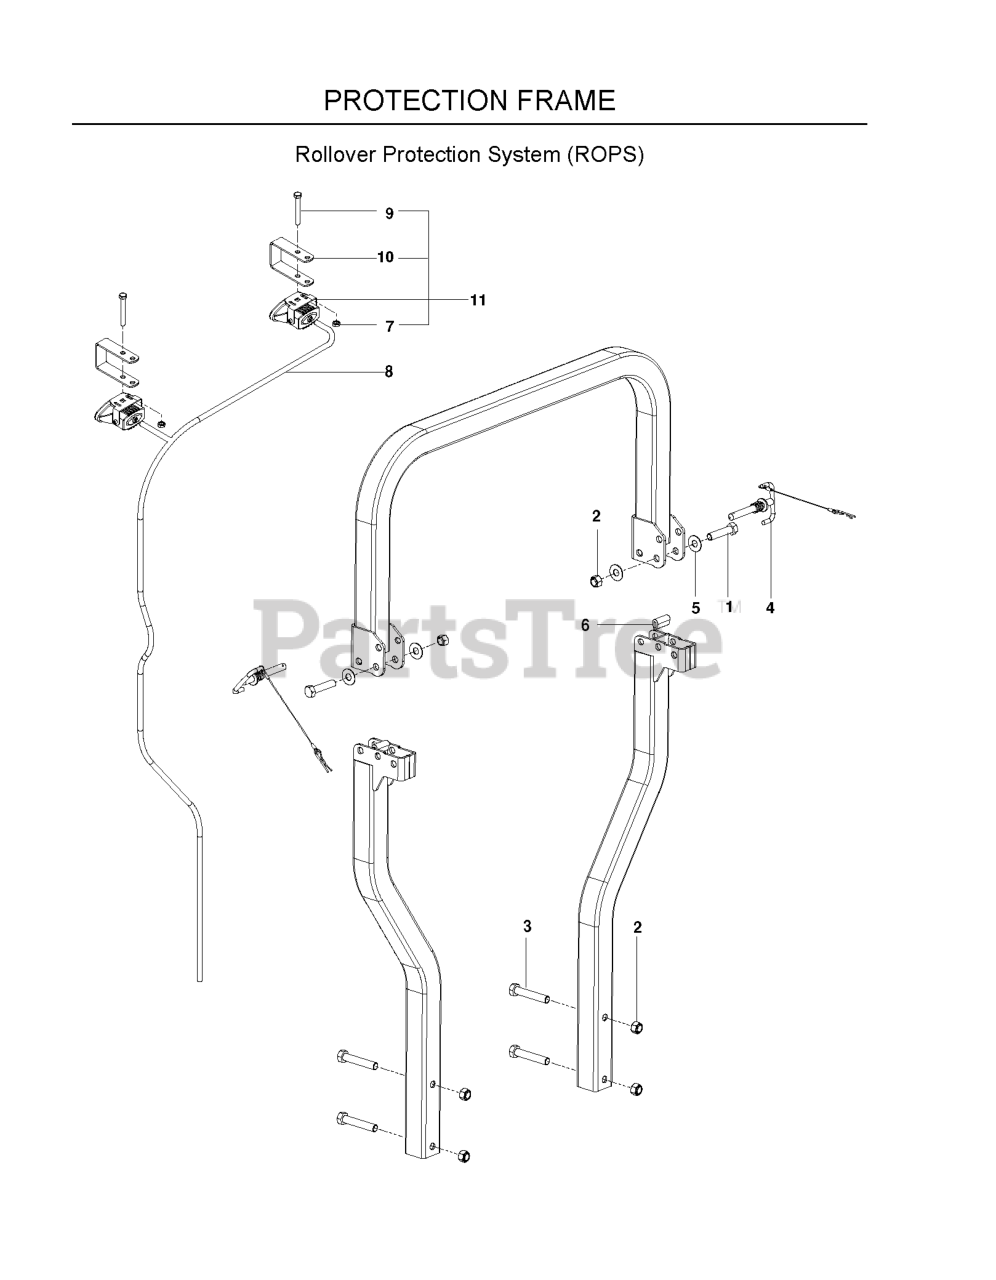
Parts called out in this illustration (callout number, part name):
1	HCS 1/2C X 3 1/4
2	NUT 1/2-13 HEX CNTRLK GR 5 ZD
3	HCS 1/2-13 X 4 GR 5 ZD
4	PIN, T HANDLE
5	PLASTIC WASHER - 1.50 OD X .53
6	RUBBER EXTRUSION - 1.40" LONG
7	NUT 5/16-18 HEX JAM ZD
8	LIGHT HARNESS
9	BOLT 5/16C X 2 1/2
10	LIGHT MOUNTING BRACKET
11	LIGHT 35W W/BRKT
